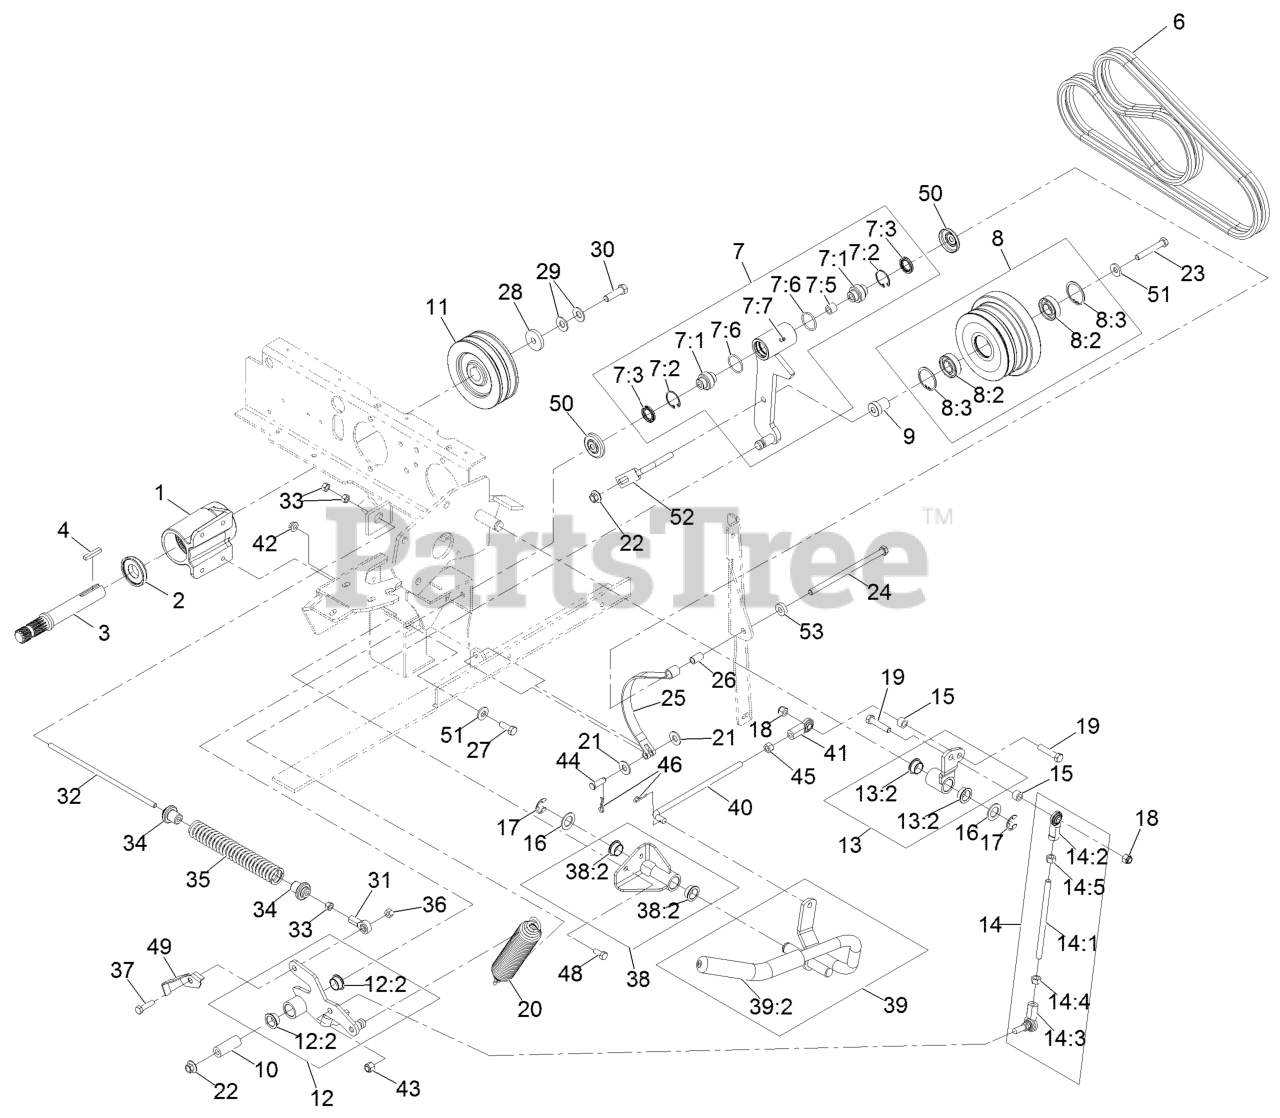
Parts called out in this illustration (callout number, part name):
2	SPACER-GUARD, BOTTOM
3	SHAFT-JACK
4	KEY-SQUARE
6	BELTS-MATCHED PAIR
7	IDLER PIVOT ASM
7:1	BEARING-SPHERICAL
7:2	RING-SNAP
7:3	SEAL-LIP, SINGLE
7:5	BUSHING-LEVER, LIFT
7:7	FITTING-GREASE
8	IDLER SHEAVE ASM
8:2	BEARING-BALL
8:3	RING-RETAINING
9	SPACER-IDLER
10	BUSHING
12	ARM ASM
12:2	BUSHING-BRONZE
13	ARM ASM
13:2	BUSHING-BRONZE
14	CLUTCH LINK ASM
14:1	ROD-LINKAGE
14:2	JOINT-BALL END, LH
14:3	BALLJOINT-RH
14:4	NUT-HEX
14:5	NUT-HEX, LH
18	NUT-LOCK, NI
19	SCREW-HH
20	SPRING-EXTENSION
21	WASHER-FLAT
23	SCREW-HH
24	SCREW-HH
25	BAND-BRAKE
27	SCREW-HH
28	WASHER-CLUTCH
29	WASHER-SPRING
30	SCREW-HH
31	BALLJOINT-RH
32	LINKAGE-ROD, PTO BRAKE
33	NUT-HEX
34	BUSHING-SPRING
35	SPRING-BRAKE
36	NUT-LOCK, NI
37	SCREW-HH
38	PIVOT ASM
38:2	BUSHING-BRONZE
39	PTO HANDLE ASM
39:2	GRIP-LEVER, CONTROL
40	LINK-HANDLE
41	JOINT-BALL, END
43	NUT-LOCK
44	PIN-CLEVIS
45	NUT-HEX
46	PIN-COTTER
48	SCREW-HH
49	SWITCH-FLAG
50	GUARD-TOP
51	WASHER-BELLEVILLE
52	GUIDE-BELT
53	SPACER
